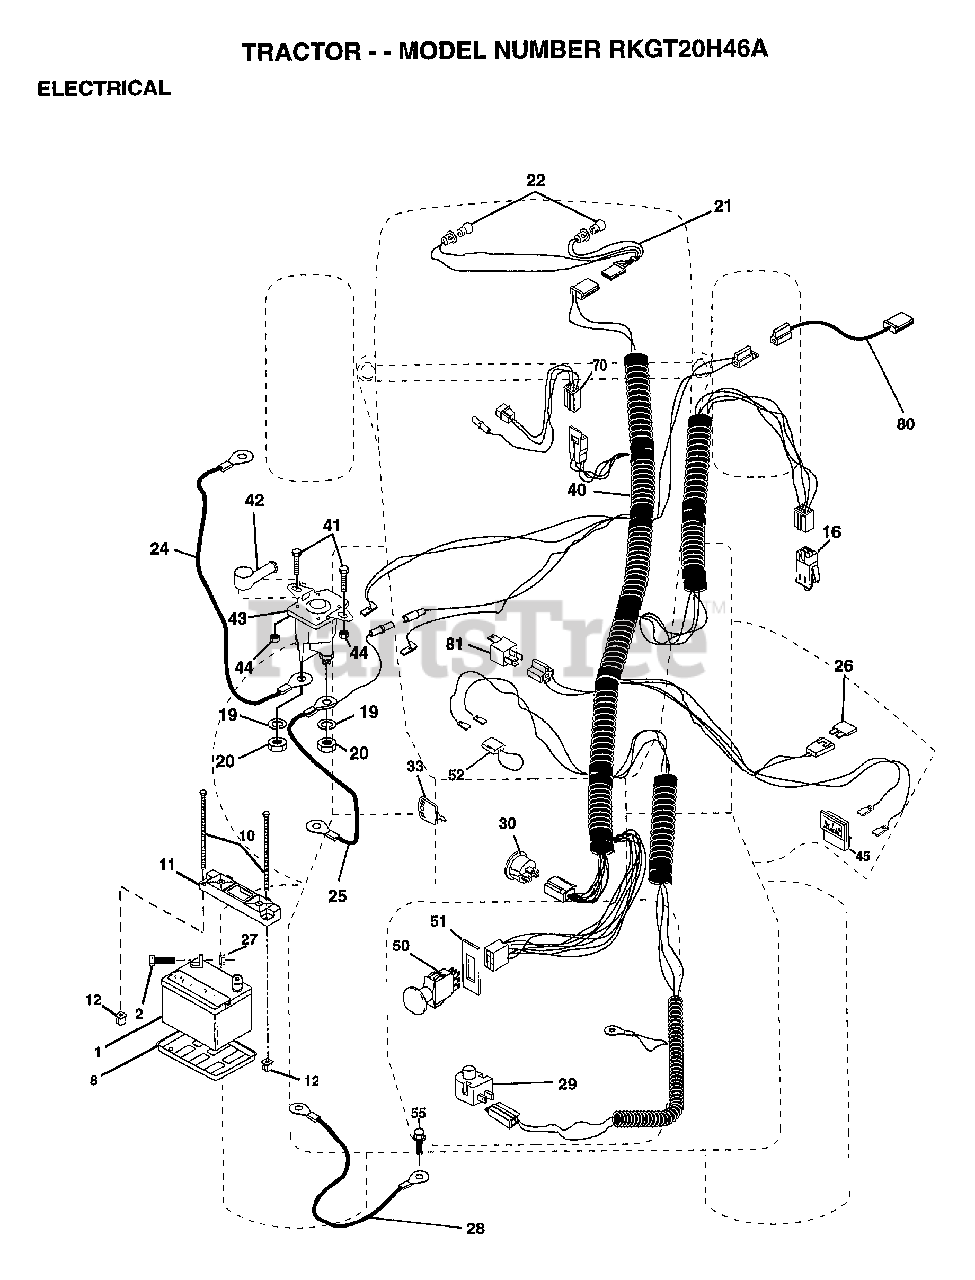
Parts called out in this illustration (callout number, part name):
2	BOLT LT
8	"TRAY T, BATTERY"
11	HOLDDOWN BATTERY
16	SWITCH INTERLOCK
20	NUT
21	HARNESS.ASM.LIGHT W/4152J
22	HEADLAMP BULB
24	CABLE-BATTERY T
25	CABLE.6GA.22W/16W
26	FUSE.15 AMP
27	NUT
28	CABLE.GRND.6GA.21
29	SWITCH.PLUNGER
30	SWITCH.IGN.
33	KEY MLD GEN DELTA
40	HARNESS.IGN.SRS.YT.ELECT.
41	BOLT HXHD FIN
44	NUT HXKEP 1/4X20
45	AMMETER
50	PTO SWITCH.BLK
51	RING RETAIN PTO
52	PROTECTION LOOP
55	SCREW LT
70	HARNESS.ENGINE
80	HARNESS.CLUT.EVX.
81	RELAY ASSY T
